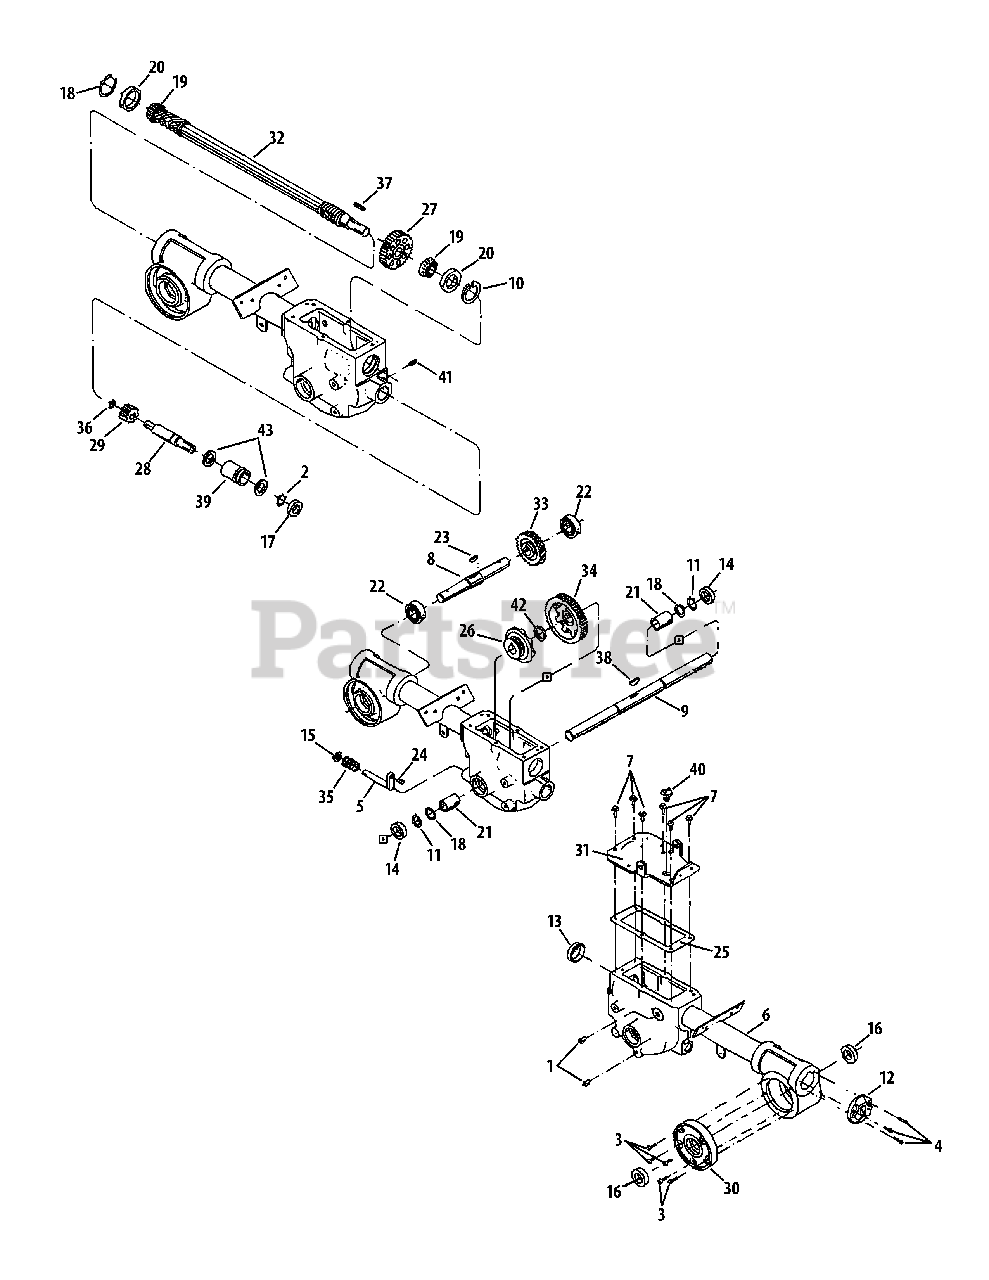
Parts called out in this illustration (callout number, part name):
1	Pipe Plug
2	Retaining Ring
3	Hex Screw, 1/4-20 x 625
4	Self-Sealing Screw, 1/4-20 x 875
5	Eccentric Shaft
6	Transmission Housing
7	Hex Flange Screw, 5/16-18 x 750
8	Tiller Shaft
9	Wheel Shaft
10	Retaining Ring
11	Retaining Ring
12	Rear Bearing Cover
13	Oil Seal, 179 x 25
14	Oil Seal, 10 x 1499
15	Oil Seal, 625 x 10
16	Oil Seal, 984 x 175
17	Oil Seal, 750 x 125
18	Washer, 1375 x 1015 x 01
18	Washer, 1375 x 1015 x 015
18	Washer, 1375 x 1015 x 03
18	Washer, 175 x 15 x 062
18	Washer, 175 x 15 x 005
18	Washer, 175 x 15 x 03
18	Washer, 175 x 15 x 01
18	Washer, 1375 x 1015 x 062
19	Cone Bearing
20	Cup Bearing
21	Bushing, 125 x 1 x 005 x 15
22	Ball Bearing
23	Woodruff Key, 25 x 112
24	Pin, 375 x 72
25	Transmission Cover Gasket
26	Wheel Drive Clutch
28	Pinion Shaft
29	Pinion Gear
30	Housing Cover
31	Transmission Cover
32	Drive Shaft
33	Worm Gear
34	Wheel Drive Gear
35	Spring, 850 x 875
36	Bowed Ring
37	Key, 188 x 1
38	Hi-Pro Key, 25 x 1312
39	Bushing, 124 x 75 x 18
41	Hex Screw, 5/16-18 x 38
42	Washer, 146 x 1016 x 062
43	Washer, 1022 x 75 x 059
